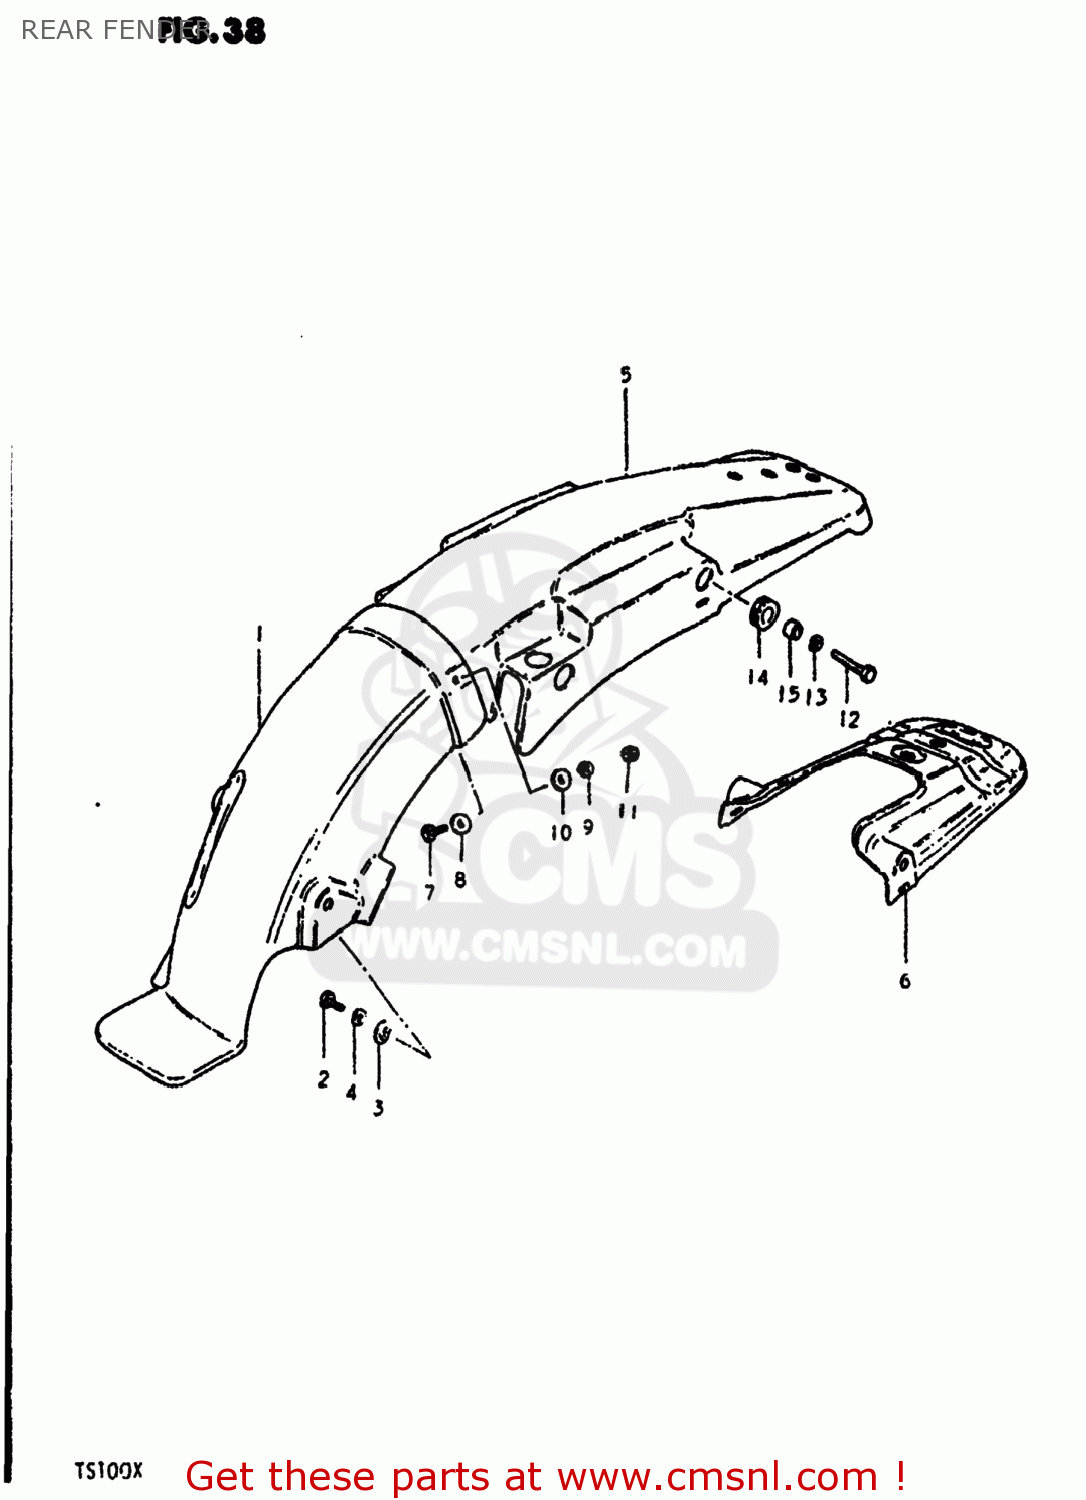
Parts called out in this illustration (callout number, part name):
1	BODY,REAR FENDER,FRONT
2	BOLT, UPPER
3	WASHER
4	LOCK WASHER
5	BODY,REAR FENDER,REAR
6	REINFORCEMENT,RR FENDER
7	BOLT
8	WASHER (5.5X16X1.2)
9	LOCK WASHER
10	WASHER(5.2X16X1)
11	NUT
12	BOLT (8X30)
13	LOCK WASHER
14	CUSHION
15	SPACER (8.2X12X7.5)
